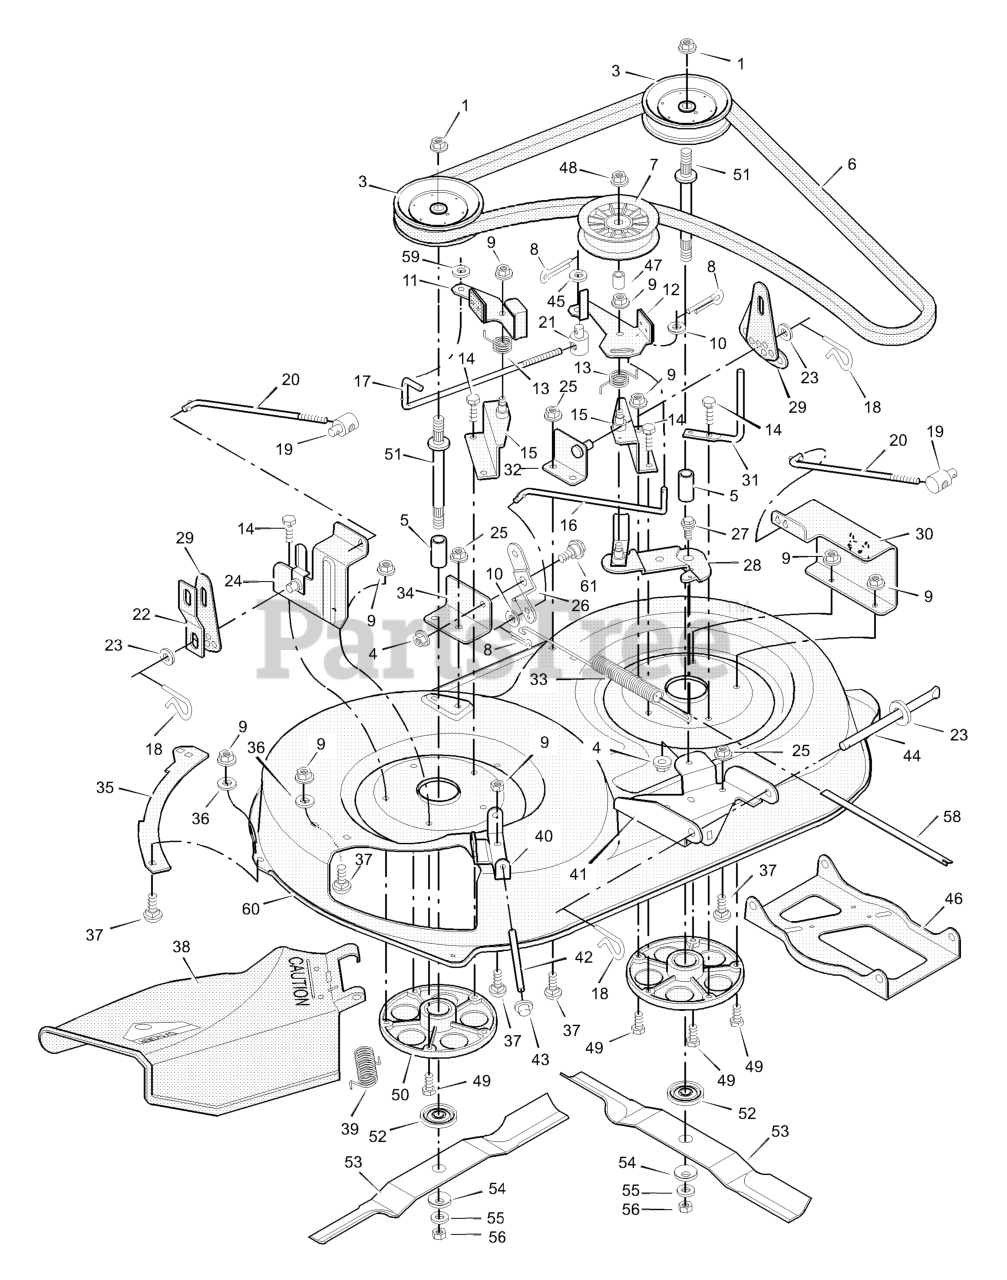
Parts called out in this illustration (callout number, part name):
1	Nut, Hex
3	Pulley, Jackshaft
4	Locknut, Flange
5	Spacer
6	Belt, Blade Drive
7	Pulley, Idler
8	Pin, Cotter
9	Locknut, Flange
11	Brake Assembly, Right
12	Brake Assembly, Left
13	Spring, Torsion
14	Bolt, Hex
15	Bracket Assembly, Brake
16	Rod, Brake
17	Rod, Cross Link
18	Pin, Hair
19	Nut, Adjustable
20	Rod, Adjuster
21	Nut, Adjustable
22	Link, Suspension
24	Bracket Assembly, Right Lifter
25	Nut, Flange
26	Bracket, Pivot
27	Bolt, Shoulder
28	Arm Assembly, Idler
29	Plate, Adjuster
30	Cover, Pulley
31	Guide, Belt
32	Bracket Assembly, Left Lifter
33	Spring, Extension
34	Bracket, Pivot
35	Plate
37	Bolt, Carriage
38	Deflector Assembly, Chute
39	Spring, Torsion
40	Bracket, Hinge
41	Bracket, Front Hanger
42	ROD, Deflector
43	Cap, Push On
44	Rod, Hanger
46	Hanger, Front
48	Nut, Flange
49	CAPSCREW, Hex Head, 5/16-18 x 1
50	Housing, Jackshaft
51	Jackshaft
52	Adapter, Blade
53	Blade, 38"
54	Washer, Belleville
56	Nut, Hex
58	Indicator, Plastic
60	Housing, Blade (38")
60	Housing, Blade (40")
61	Bolt, Shoulder
